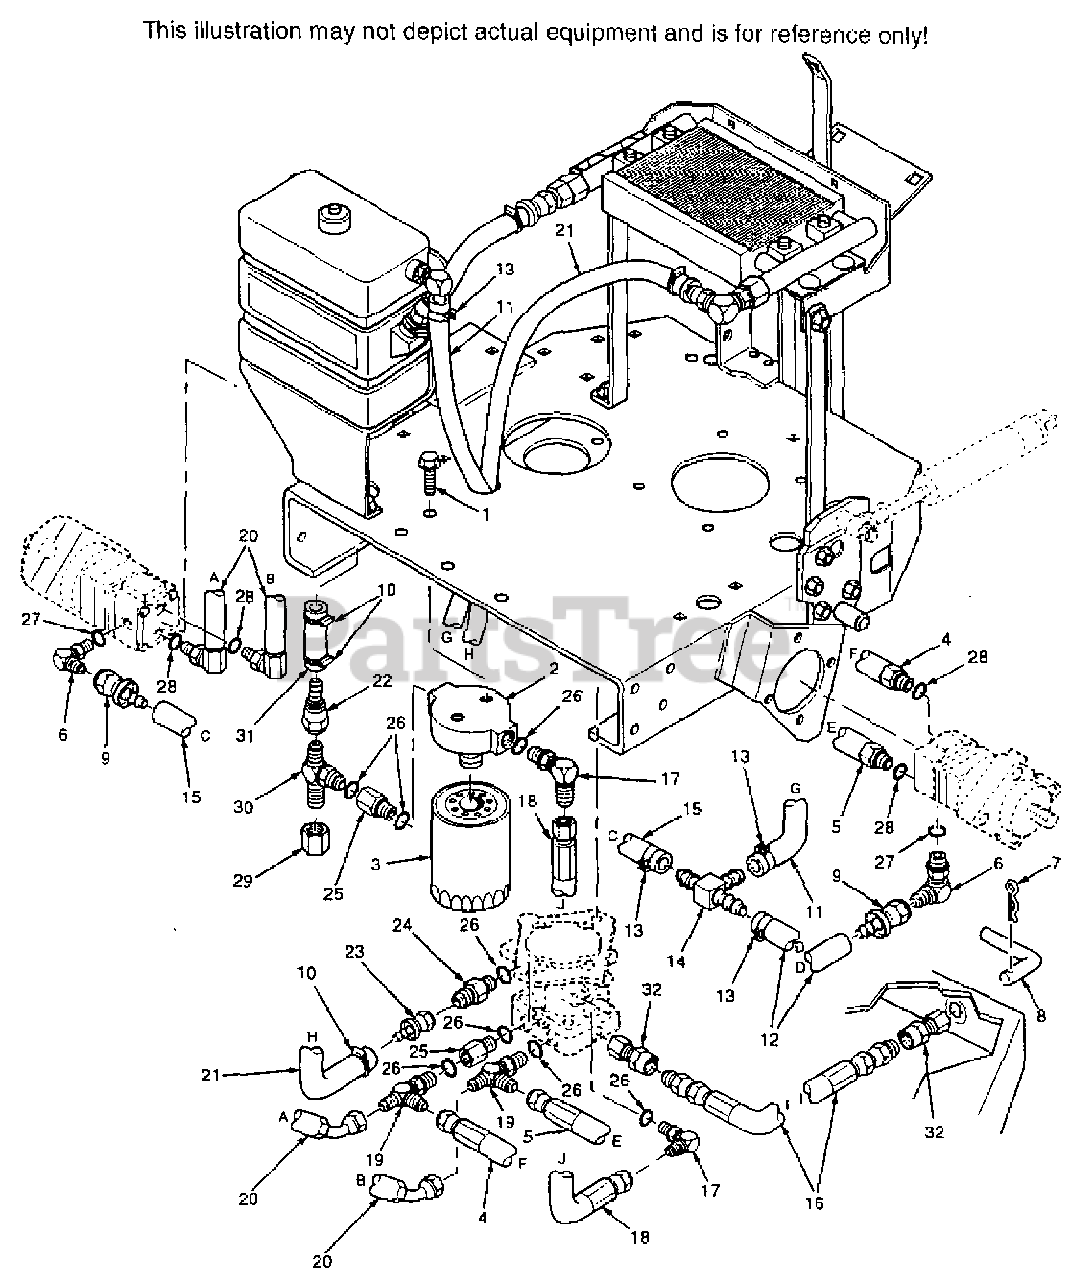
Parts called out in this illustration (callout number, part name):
1	SERR. FL. HEX HEAD CPSCR, 1/4-20 X 1/2
2	FILTER HEAD
3	FILTER SPIN-ON LUBE
4	HOSE ASSEMBLY
5	HOSE ASSEMBLY
6	ELBOW, 90 DEGREES
7	PIN, COTTER
8	LEVER, DUMP VALUE
9	CONNECTOR, FLARE SWIVEL WITH HOSE BARB
10	CLAMP, HOSE
11	HOSE, 1/4 PUSHLOCK
12	HOSE, 1/4 PUSHLOCK
13	CLAMP, HOSE
14	TEE UNION, PUSHLOCK HOSE
15	HOSE, 1/4 PUSHLOCK
16	HOSE, DUMP VALUE
18	INLET HOSE, 3/4" ID
19	TEE, 1/2" RUN
20	MOTOR HOSE
21	HOSE, PUMP TO OIL COOLER
22	COUPLING, FLARE SWIVEL
23	COUPLING, FLARE SWIVEL WITH HOSE BARB
24	TUBE UNION
25	O-RING BUSHING
26	O-RING
27	O-RING
28	O-RING
30	TEE, JIC TO O-RING
31	HOSE
32	COMPRESSION FITTING
